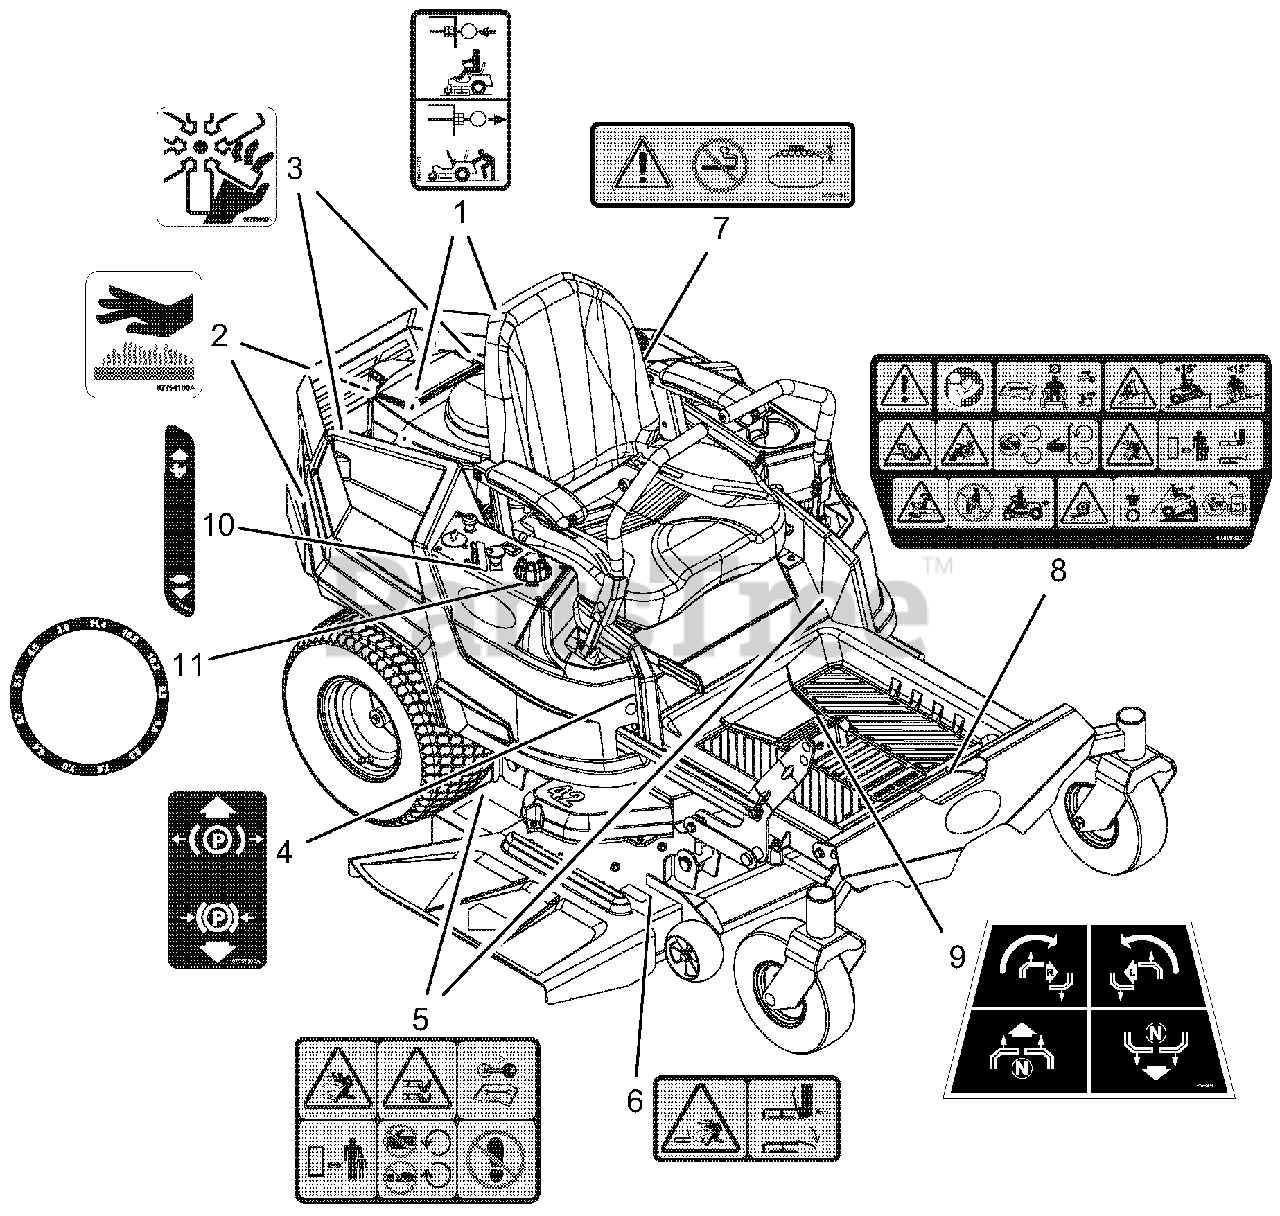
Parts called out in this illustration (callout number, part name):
1	DECAL, TRANSMISSION DISCONNECT
2	DECAL, HOT SURFACE
3	DECAL, DANGER FAN
4	DECAL, PARKING BRAKE LEVER
5	DECAL, SAFETY - MOWER DECK
6	DECAL, SAFETY - DECK GUARDING
7	DECAL-FUEL, WARNING
8	DECAL, MAIN SAFETY
9	DECAL, STEERING
10	DECAL, DASH DECAL
11	DECAL, CUT HEIGHT - IKON CE
